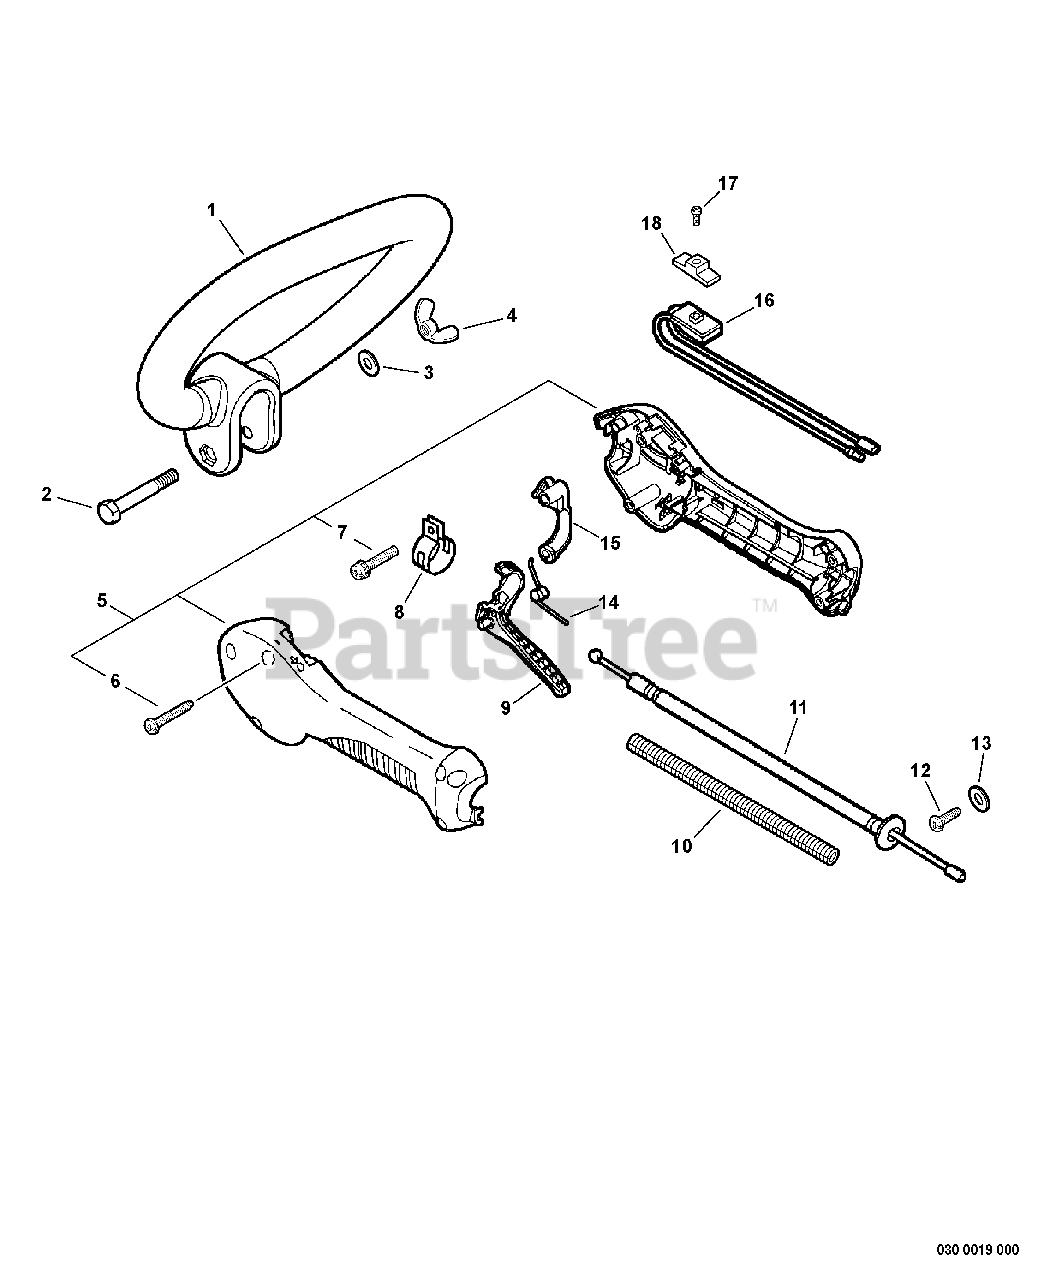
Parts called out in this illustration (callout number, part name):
1	HANDLE - FRONT
2	BOLT - 1/4-20 X 2"
3	WASHER - 1/4"
4	WINGNUT - 1/4-20
5	CONTROL HANDLE KIT
6	SCREW - 5X20
7	SCREW - 5X20
9	TRIGGER, THROTTLE
10	TUBE, PROTECTIVE - CORRUGATED
11	CABLE, THROTTLE
12	SCREW - 5X12
14	SPRING, TRIGGER
15	LOCKOUT, THROTTLE
16	IGNITION SWITCH ASSY
17	SCREW - 3X10
18	KNOB, SWITCH - ORANGE
